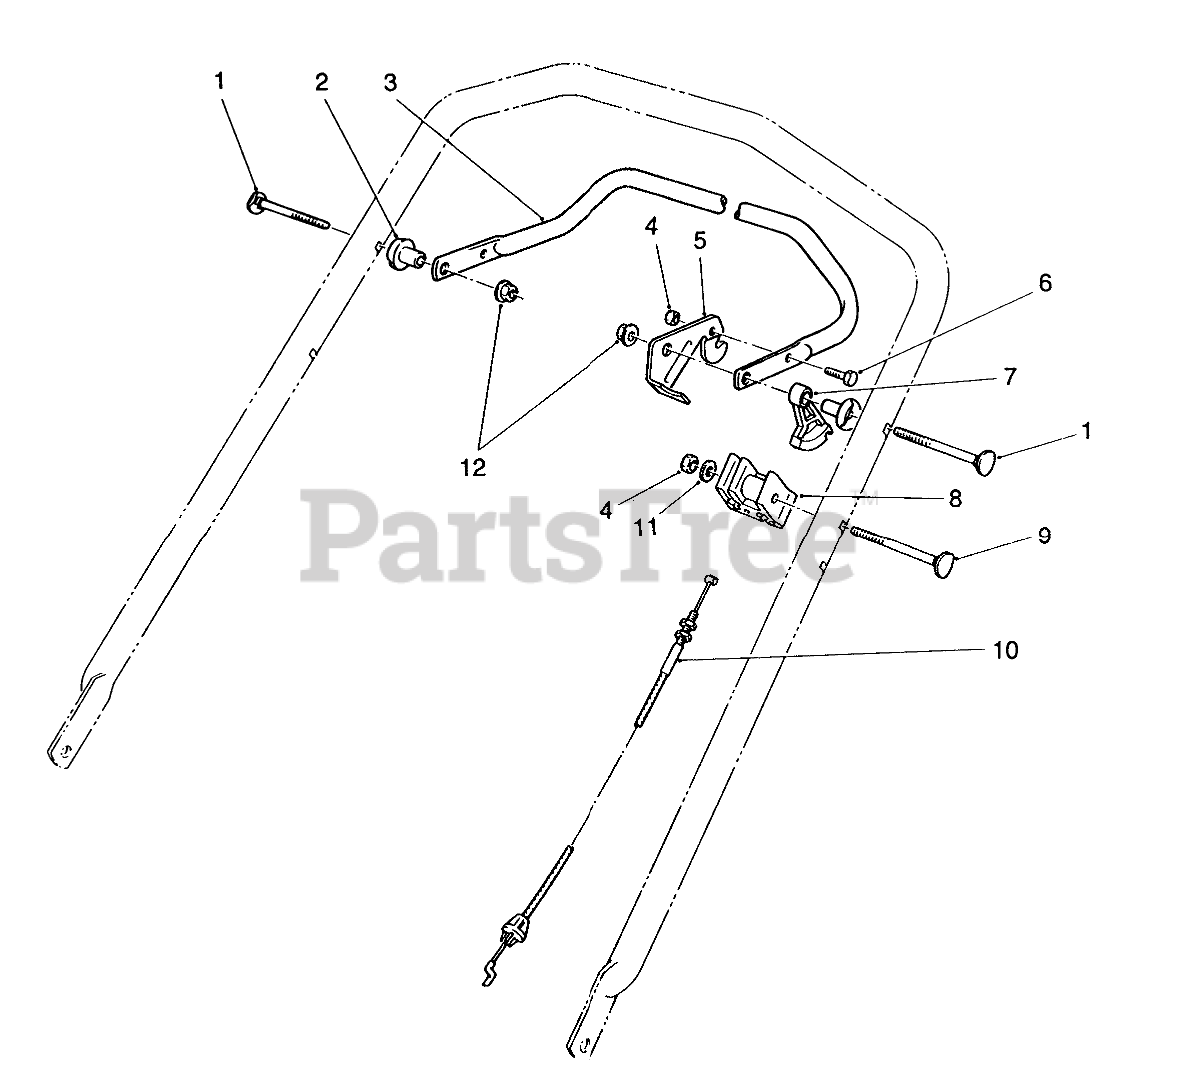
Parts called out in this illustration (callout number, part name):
1	SCREW-HANDLE
2	SPACER-SUPPORT
3	Bar-Control
4	NUT-LOCK, NI
5	CONTROL LEVER
6	SCREW-HH
7	LEVER-TRACTION
8	SUPPORT-CABLE
9	SCREW-HANDLE
10	TRACTION CABLE
11	WASHER-FLAT
12	NUT-LOCK, NI
